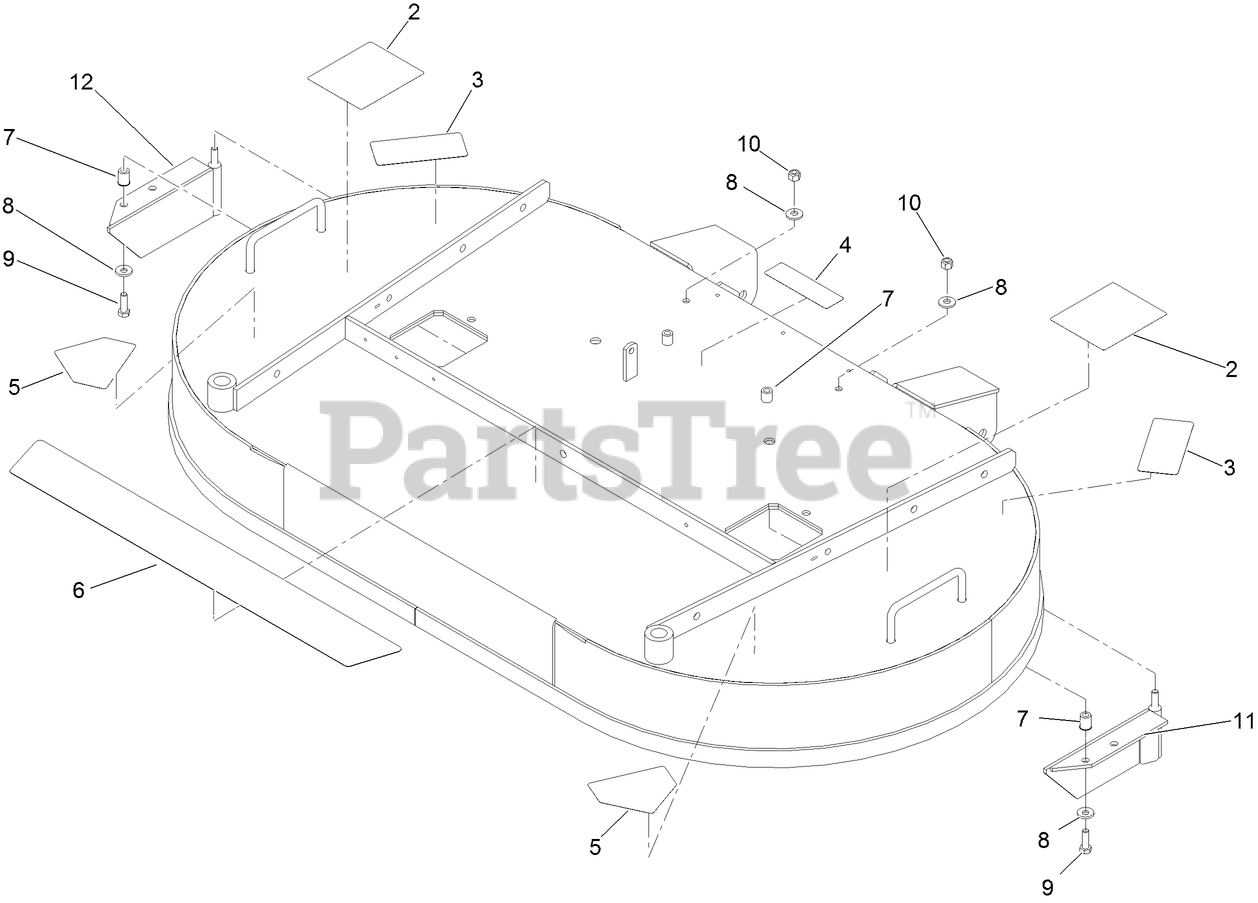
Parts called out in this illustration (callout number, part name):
2	DECAL-HEIGHT ADJUST, CUTTING
3	DECAL-TORQUE, BLADE BOLT
4	DECAL-COVER, MISSING
5	DECAL-DANGER
6	PAD-ANTI SKID
7	NUT-CLINCH
8	WASHER-SPRING
9	SCREW-HH
10	NUT-LOCK, NI
11	BAFFLE-LH
12	BAFFLE-RH
